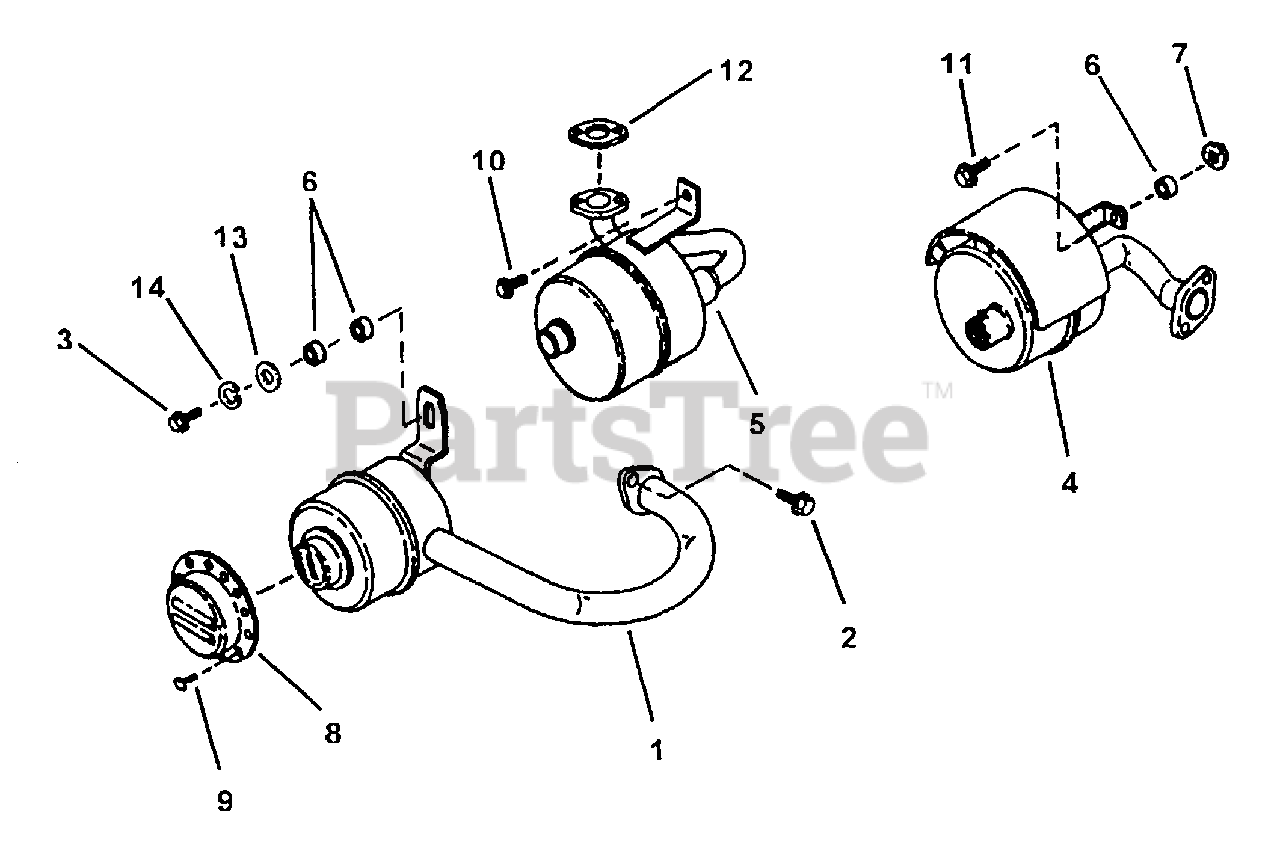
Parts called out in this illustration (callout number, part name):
1	MUFFLER
2	SCREW, 5/16-18 x 3/4" Hex Head Cap, Grade 2
3	SCREW, 1/4-20x1-1/4" Hex Head Cap
4	MUFFLER
5	MUFFLER
6	SPACER
7	NUT, 1/4-20 Hex Flange Lock
8	DEFLECTOR, Heat
9	SCREW #8-18 x 3/8" Type AB Modified
10	SCREW, 1/4-20 x 5/8" Hex Washer Self-Tap
11	SCREW, 1/4-20 x 3/4" Hex Head Cap, Grade 5
12	GASKET, Muffler
13	WASHER, 1/4" Flat
14	WASHER, 1/4" Split Lock
